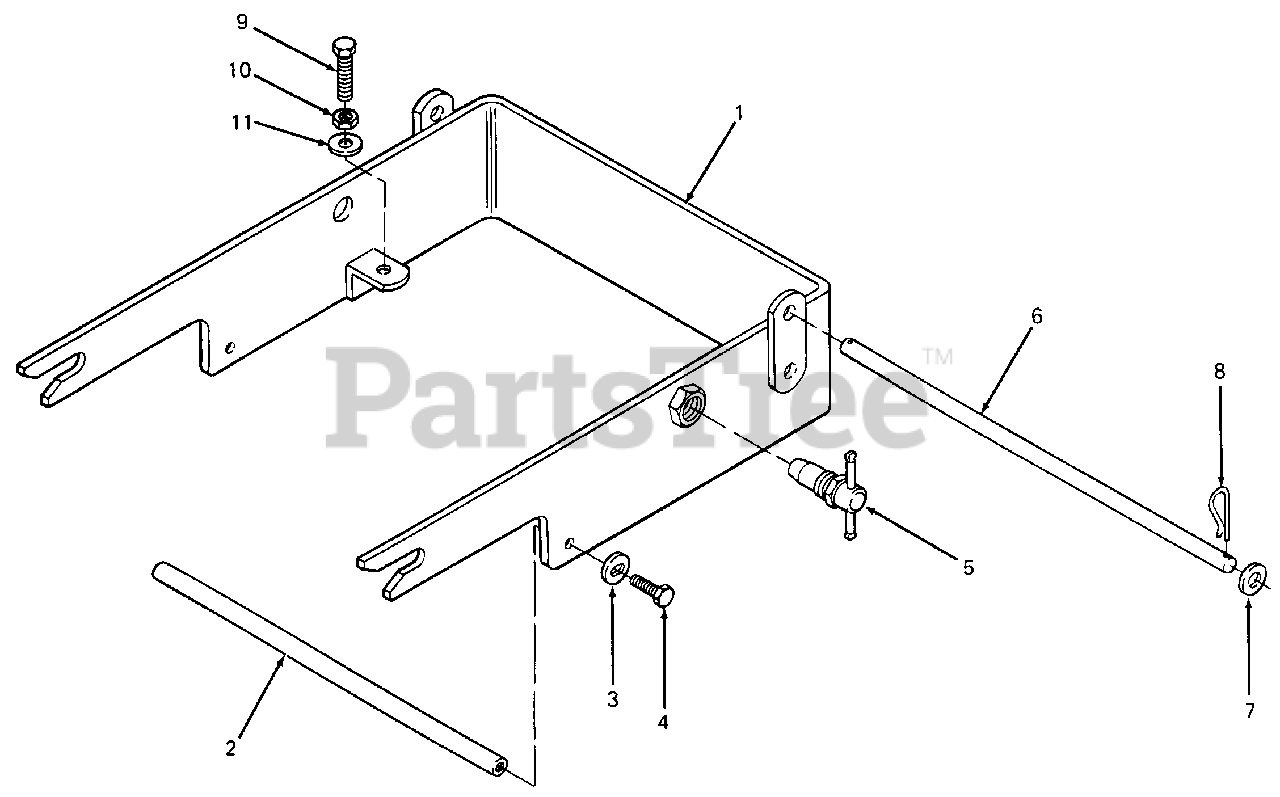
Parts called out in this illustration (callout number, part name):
1	Bracket Assy, Front Weight
2	Rod, Carriage Bracket Support, .50 Dia
3	Washer, Bell
4	Screw, Hex, 5/16-24 X 1.0
5	Pin, Threaded, 3/4-16 X 1.43 Lg
6	Rod, .50 Dia X 15.0 Lg
7	Washer, Flat, .510 X 1.0 X .06
8	Pin, Cotter
9	Bolt, Hex, 3/8-16 X 1.25 Lg GR 5
10	Nut, Hex Jam, 3/8-16
11	Washer, Flat, .40 X .88 X .06 HDN
